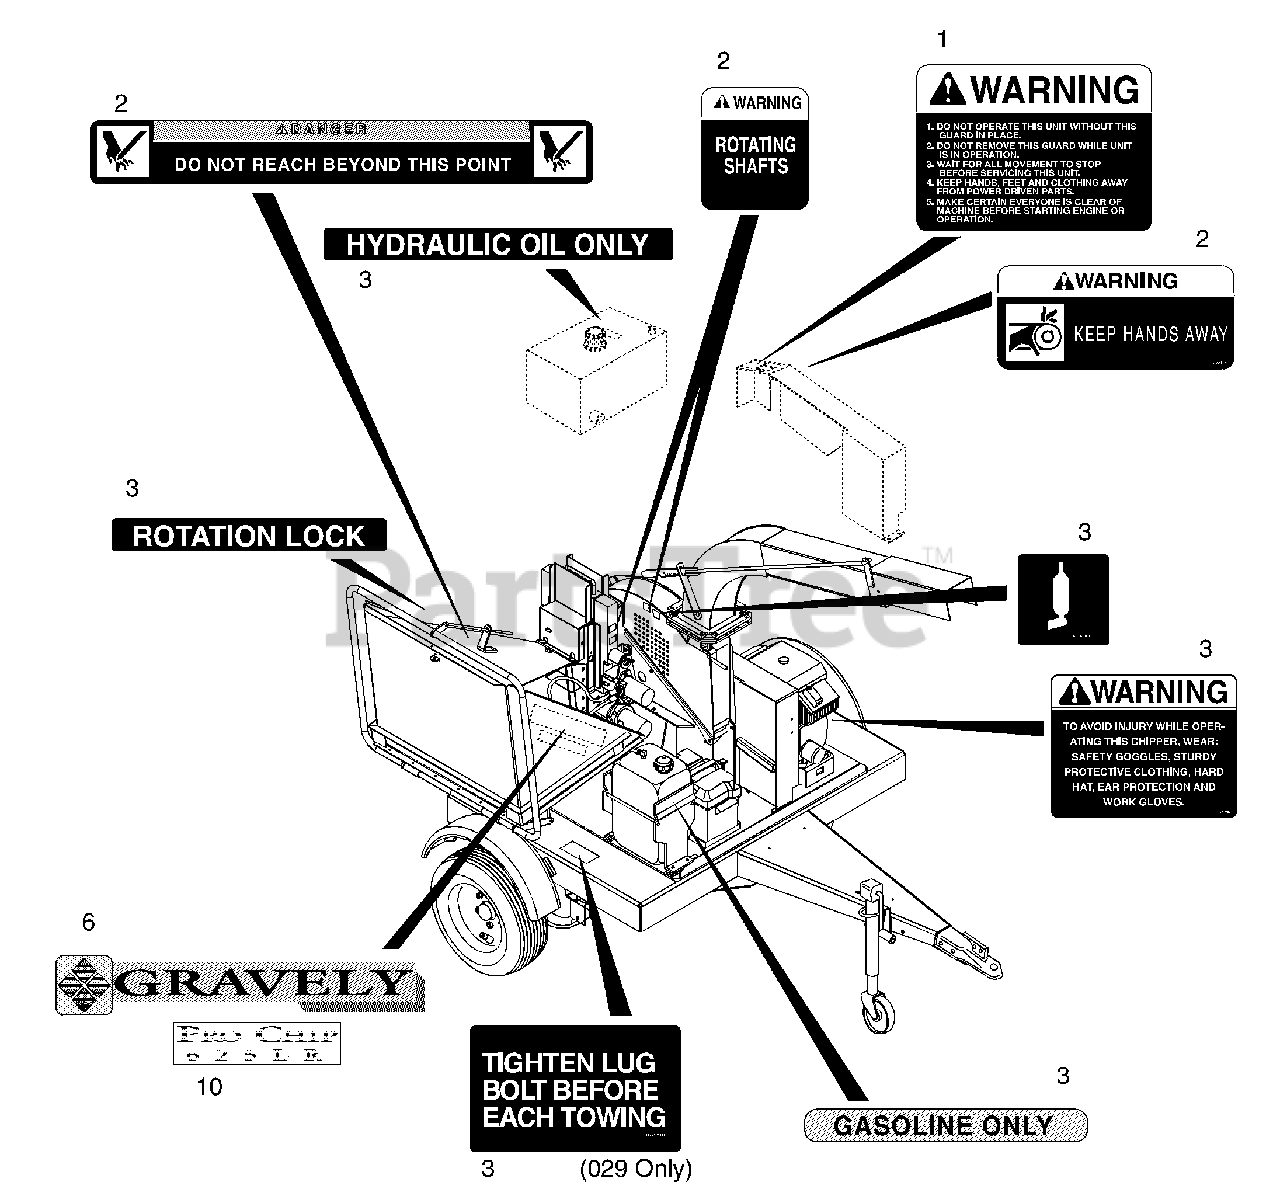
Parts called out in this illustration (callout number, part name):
1	Decal Set
2	Decal Set Large Chipper
3	Decal Set Chipper Blk/Wht
4	Decal - Warning, Start Engine
5	Decal - Warning, Tipping
6	Gravely Name Logo Set
7	Decal - Pro Chip 625LR
8	Decal - Warning, Protective
9	Decal - Hot Surface
10	Decal - Model Designation 625LR
